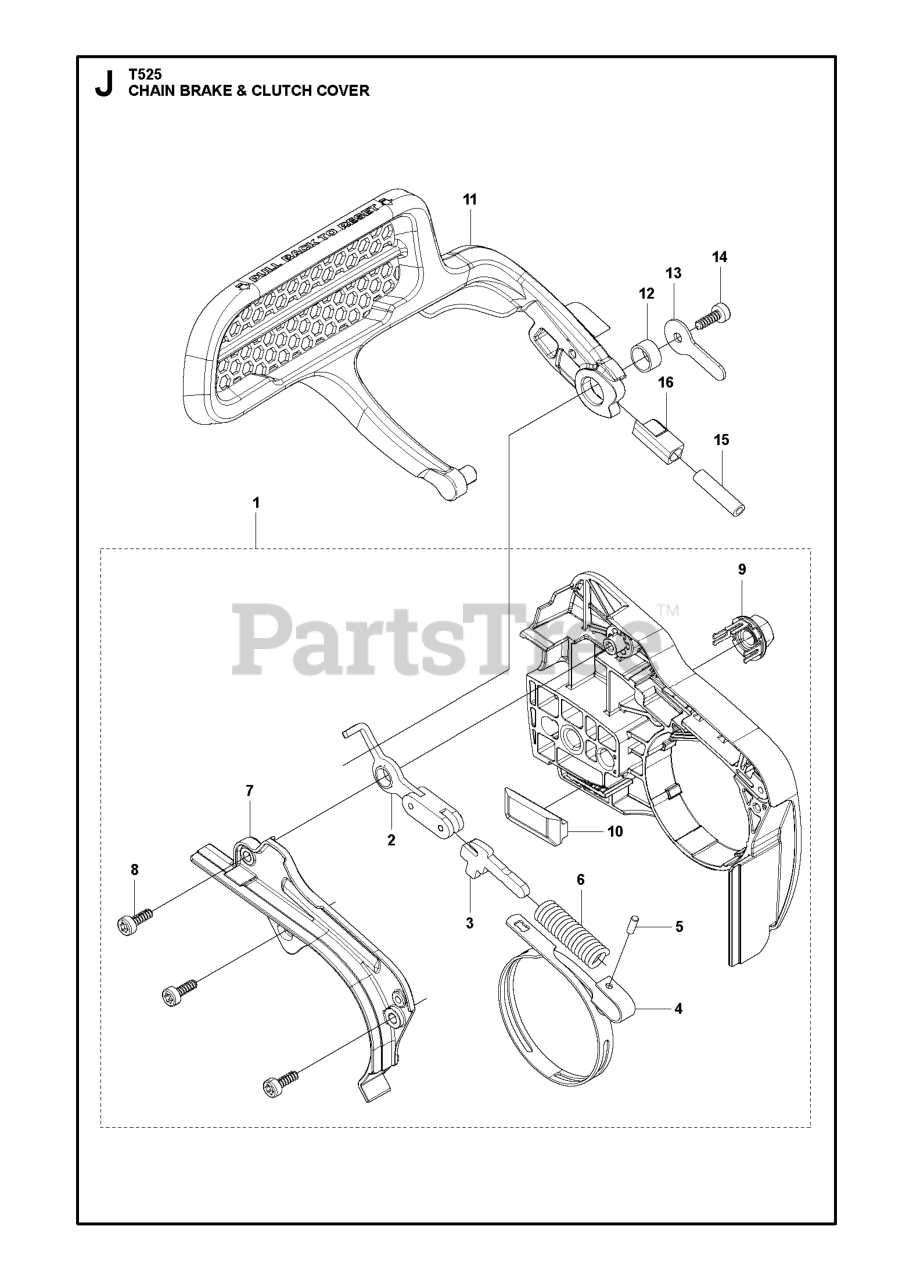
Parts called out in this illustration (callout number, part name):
1	CHAIN BRAKE ASSY
2	KNEE JOINT ASSY
3	ARM
4	BRAKE BAND
5	ROLLER
6	BRAKE SPRING
7	COVER LID ORANGE
8	SCREW TP4-18X12 LOCK
9	NUT RETAINER ASSY
11	HAND GUARD GRAY
12	SPACER L=6.25
14	SCREW TP4-18X12 LOCK
